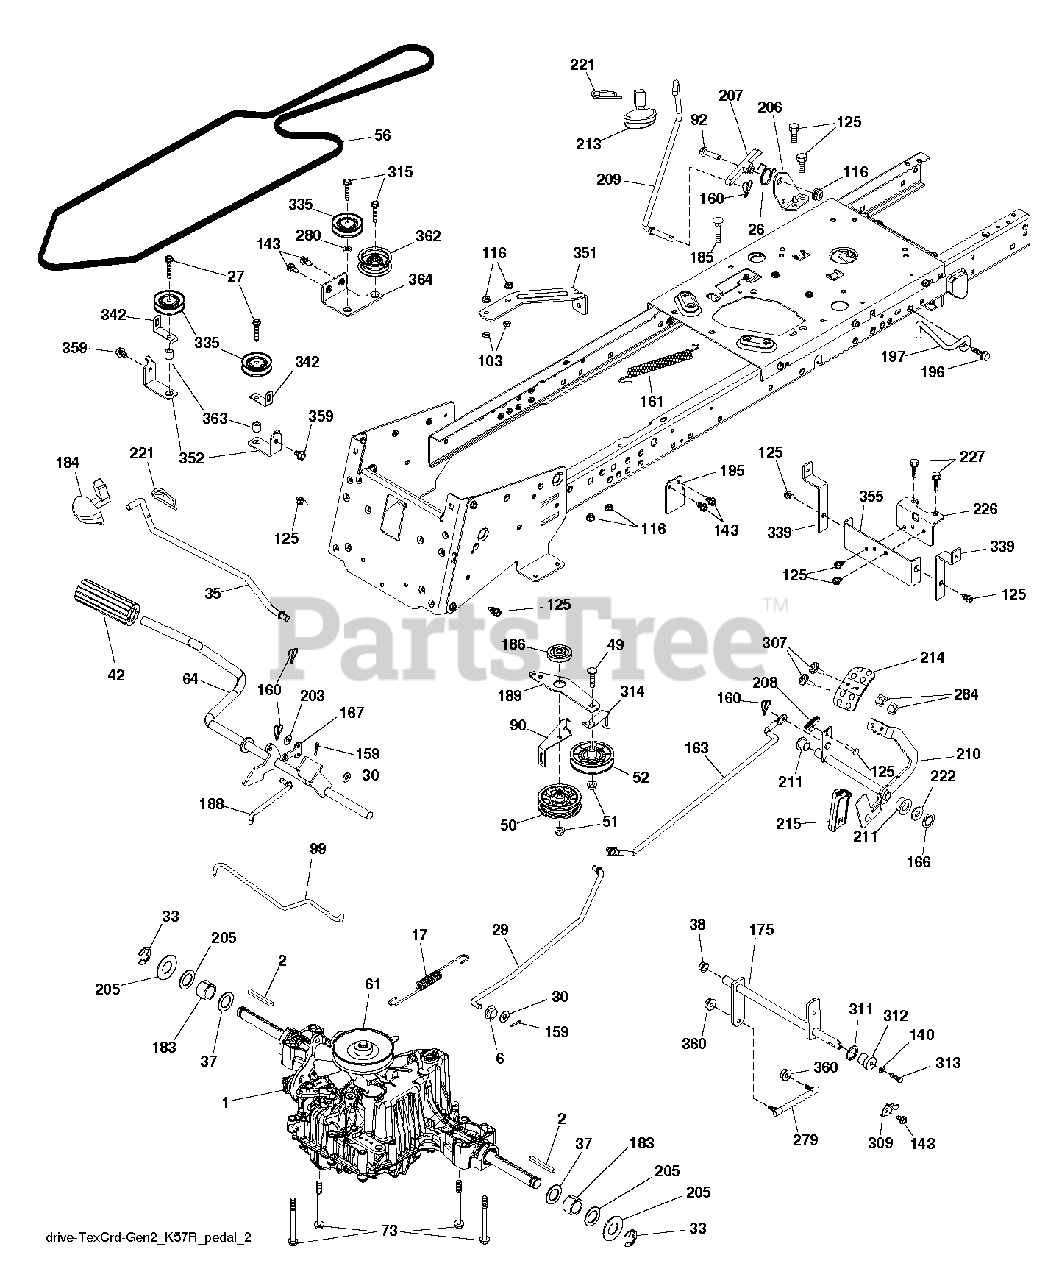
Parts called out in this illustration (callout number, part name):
2	SQUARE KEY
6	BUSHING.SNAP.NYL.BLK.
17	SPRING
26	SPRING.RETURN.CRUISE
29	ROD ROD BRAKE K46 TCRD GEN 2
30	WASHER
35	ROD .BRAKE. PARKING. GT. HUSQ.
37	WASHER.HARDENED
38	NYLINER SNAP 5/8" ID
42	PEDAL COVER T
50	IDLER.FLAT.910.OFFSET
51	NUT LOCK FLG 3/8-16 UNC
52	IDLER.V-GROOVE.910.OFFSET
56	BELT BELT DRIVE GROUND 114.25
61	PULLEY PULLEY INPUT FLANGED TR
64	SHAFT.ASM.PEDAL.BRK.CNTR
73	BOLT HEX 5/16-18 GR 5
90	KEEPER KEEPER BELT CLUTCHING T
92	BOLT
99	ROD ROD BYPASS CRD TEX GEN 2
103	JAM NUT TI
116	NUT LOCK HEX FLANGE 5/16-18
125	SCREW
140	LOCKWASHER
143	SCREW LT
159	COTTER PIN
160	RETAINER CLIP
161	SPRING, RETURN LT
163	ROD ROD CONTROL SHIFT PEDAL TC
166	NUT.PUSH.625
167	LATCH.BRAKE.SPRING
175	SHAFT SUBASM.SHAFT.CROSS.SHIFT
183	SPACER AXLE
184	RB HANDLE.PARKG.BRK.HUS/PRED
186	SPACER.RETAINER
188	RP LINK.CLUTCH.GROUND.DRIVE
189	BELLCRANK BELLCRANK GROUNDDRI
195	BRACKET.ROD.BRAKE
196	SCREW 3/8-16X1
197	LINK.CLUTCH.ANIT-ROTAT
203	WASHER
206	BRACKET.MOUNT.CRUISE.LATCH
207	LATCH.CONTROL.CRUISE
208	GEAR.SECTOR.CONTROL.CR
209	ROD.CONTROL.CRUISE.GT.
210	ROCKER.ASM.PEDAL.CONTR
211	BEARING.NYLON
213	KNOB.CONTROL.CRUSIE.HU
214	PEDAL.FORWARD.HUSQVARNA.DEALER
215	PEDAL RUBBER REVERSE
221	RETAINER.SPRING.CLIP.H
222	WASHER 21/32 X 1-1/4 X 10 GA.
226	BRACKET.MOUNT.TORQUE.K46.TLT
227	SCREW
279	LINK SUBASM. LINK AND STUD
284	NUT.U-CHNL.1/4-20.550DP.350PNL
307	SCREW.MACHINE.CR.1/4-20
309	PLATE FASTENING LT
311	WASHER NYL
312	HUB.TAPERED.ROUND.CRD
314	RETAINER KEEPER BELT
315	BOLT.5/16-18X1.25
335	PULLEY.V-IDLER.
339	STRAP STRAP TORQUE K46 CRD TE
342	BELT GUIDE
351	BRACKET BRACKET DECK SWAY
352	BRACKET BRACKET IDLER CRD TEX
355	STRAP STRAP TORQUE K46 CRD TEX
359	SCREW LT.3/8-46X5/8
360	NUT NUT HEX CENTERLOCK 5/16-24
362	IDLER.FLAT.2.25.INCH
363	SPACER SPACER 343X63X.62
364	BRACKET BRACKET IDLER CRD TEX
